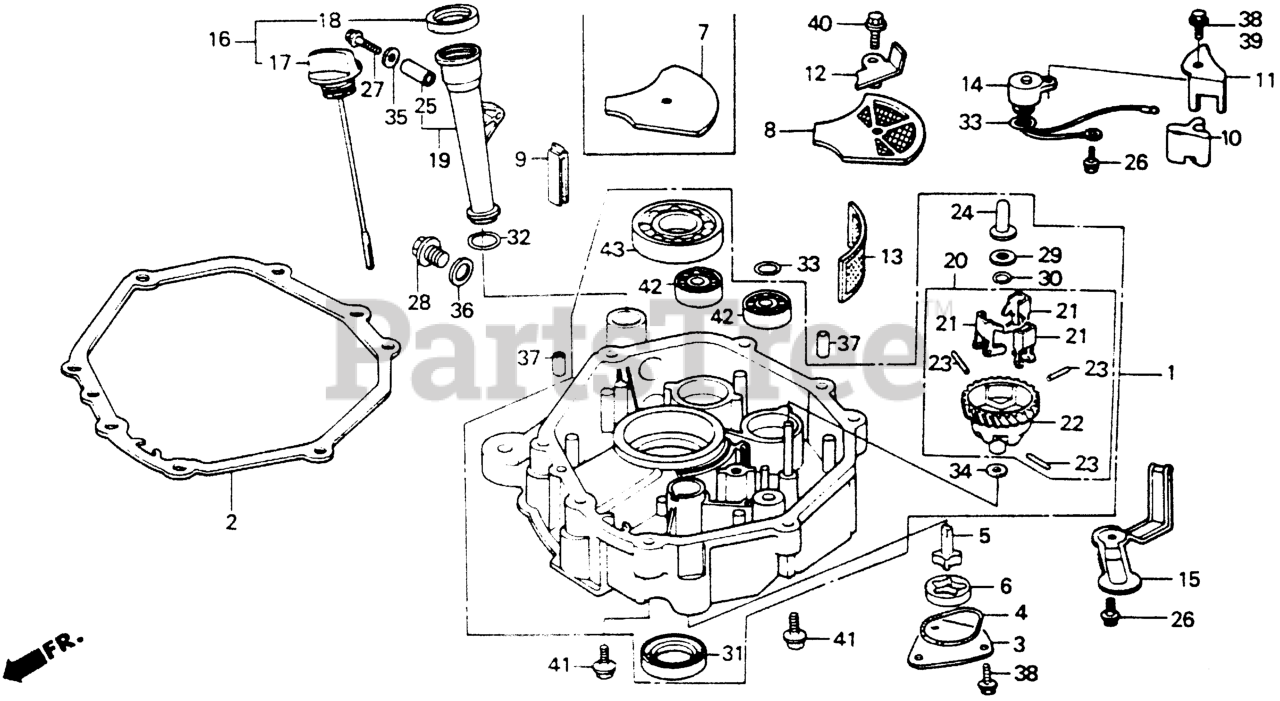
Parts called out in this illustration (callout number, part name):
1	PAN ASSY., OIL
2	GASKET, OIL PAN
3	COVER, OIL PUMP
4	O-RING, PUMP COVER
5	ROTOR (INNER)
6	ROTOR, OIL PUMP (OUTER)
8	PLATE, OIL FILTER
9	RUBBER, OIL RETURN
10	STOPPER, OIL
11	PLATE, OIL STOPPER
12	PLATE, SUCTION
13	SCREEN, OIL FILTER
14	SWITCH, OIL LEVEL
15	PROTECTOR, SWITCH
16	CAP ASSY., OIL FILLER
17	DIPSTICK, OIL (NOT AVAILABLE)
18	GASKET, OIL FILLER CAP
19	EXTENSION, OIL FILLER
20	GOVERNOR ASSY.
21	WEIGHT, GOVERNOR
22	HOLDER, GOVERNOR WEIGHT
23	PIN, GOVERNOR WEIGHT
24	SLIDER, GOVERNOR
25	COLLAR, EXTENSION Use up to Engine SN 1257294.
26	BOLT, FLANGE (6X12) (CT200)
27	BOLT, FLANGE (6X32)
28	BOLT, DRAIN PLUG (20MM)
29	WASHER (6X16)
30	CLIP, GOVERNOR HOLDER
31	OIL SEAL (30X46X8)
32	O-RING (22.45X2.2)
32	O-RING (22.5X2.2) Use from Engine SN 1257295.
33	O-RING (11.8X2.4)
34	WASHER, PLAIN (6MM)
35	WASHER, PLAIN (6MM)
36	WASHER, DRAIN PLUG (20MM)
37	PIN A, DOWEL (8X14)
38	BOLT, FLANGE (6X12) Use up to Engine SN 1543277.
39	BOLT, FLANGE (6X16) Use from Engine SN 2056820.
40	BOLT, FLANGE (6X25)
41	BOLT, FLANGE (8X40)
42	BEARING, RADIAL BALL (6202)
43	BEARING, RADIAL BALL (6206)
